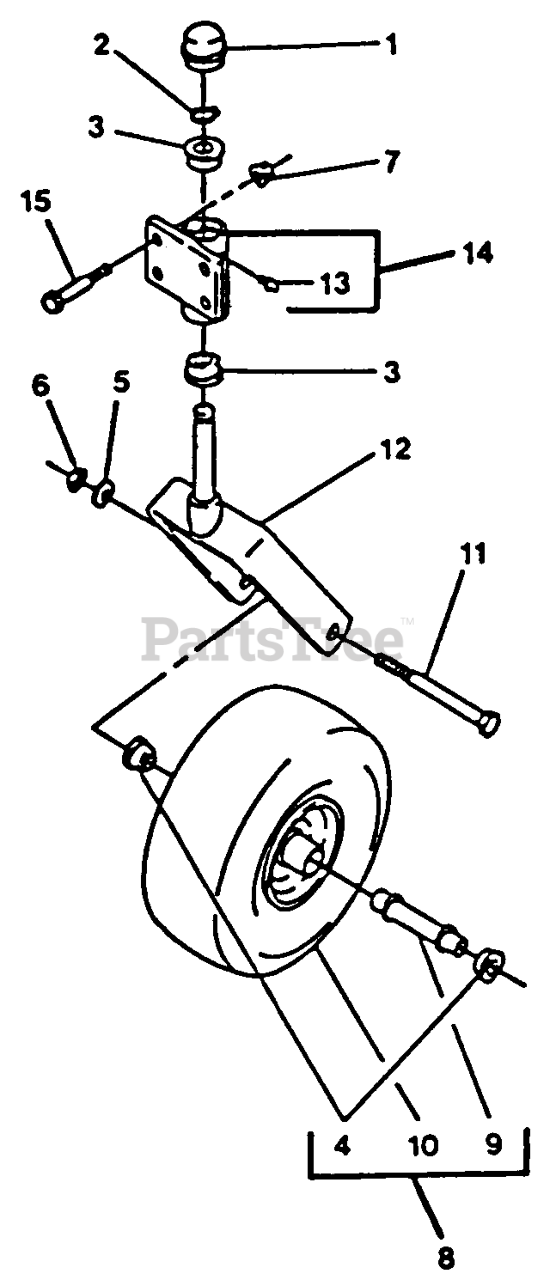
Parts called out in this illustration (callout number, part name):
1	CAP,GREASE
3	BEARING,FLANGED
9	SPACER WLDMT,WHEEL
12	WLD,CASTER FORK
14	WLD,CASTER MOUNT
